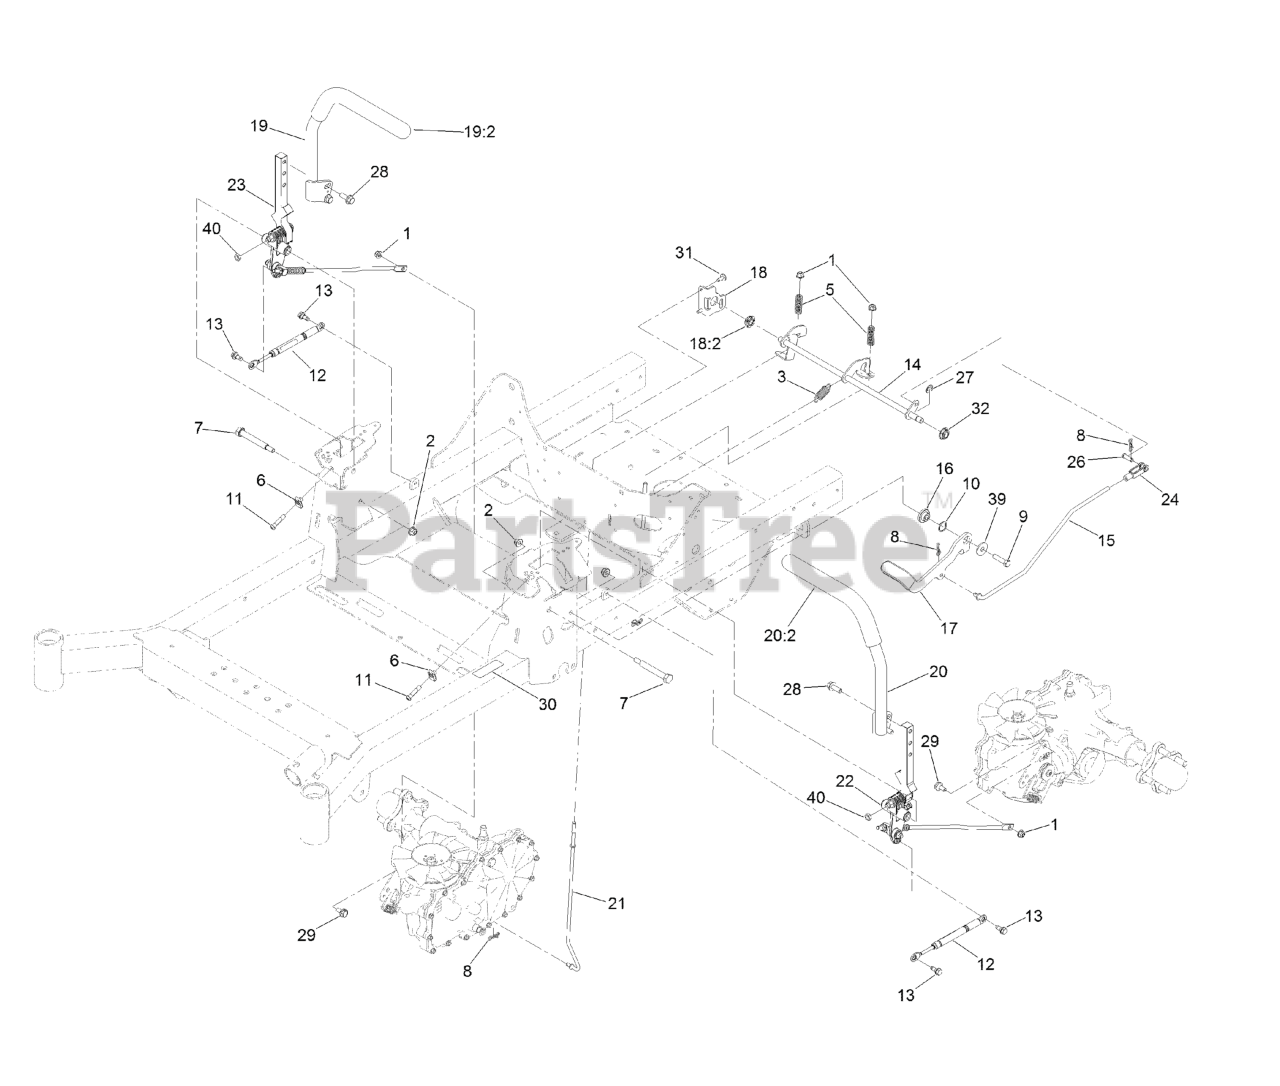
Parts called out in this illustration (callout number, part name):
1	NUT-HF, NI
2	NUT-HF, NI
3	SPRING-EXTENSION
5	SPRING-COMPRESSION
7	BOLT-PIVOT
8	PIN-COTTER, LOCKING
9	SCREW-HH
10	WASHER-WAVE
11	SCREW-HSBH
13	SCREW-SHOULDER
14	SHAFT-BRAKE
15	LINKAGE-BRAKE, UPPER
16	PIVOT-FLANGE
17	LEVER-BRAKE (WITH GRIP)
18	BRACKET-BRAKE
18:2	BEARING-SPHERICAL
19	RH CONTROL HANDLE ASM
20	LH CONTROL HANDLE ASM
21	LINKAGE-BRAKE, LOWER
22	LH Motion Control ASM
23	RH Motion Control ASM
24	YOKE-ADJUSTABLE
26	PIN-CLEVIS
27	RING-RETAINING, EXTERNAL
28	SCREW-HHF 3/8-16 X 1
29	BOLT-SHOULDER,HFH
30	DECAL-BRAKE, PARKING
31	SCREW-TORX
32	BEARING-SPHERICAL
39	WASHER
40	NUT-JAM
